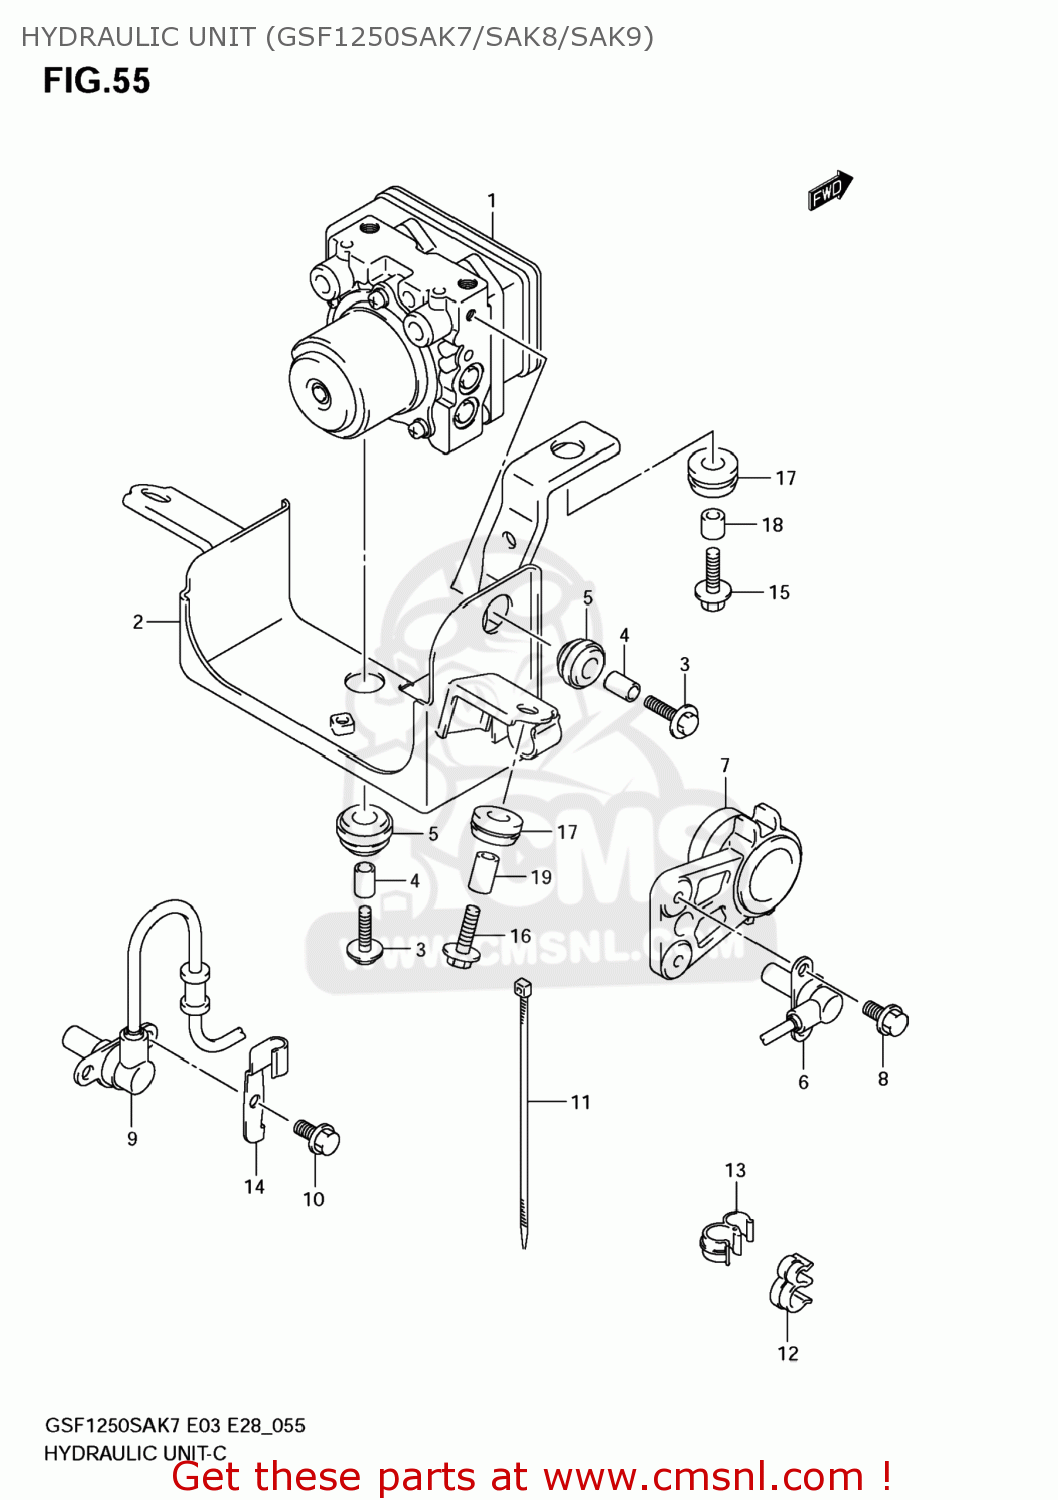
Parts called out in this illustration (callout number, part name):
1	UNIT ASSY,HYDRAULIC ABS
2	HOLDER,HYDRAULIC UNIT ABS
3	BOLT,HYDR UNIT MTG
4	SPACER,HYDR UNIT MTG
5	RUBBER,HYDR UNIT MTG
6	SENSOR,FR WHEEL ABS
7	BRACKET,SPEED SENSOR FR
8	BOLT(6X12)
9	SENSOR,RR WHEEL ABS
10	BOLT
11	CLAMP(L:145)
12	CLAMP
13	CLAMP
14	CLAMP,ABS SENSOR RR
15	BOLT(6X20)
16	BOLT(6X25)
17	CUSHION
18	SPACER(6.5X9X8)
19	SPACER(6.5X9X11.5)
